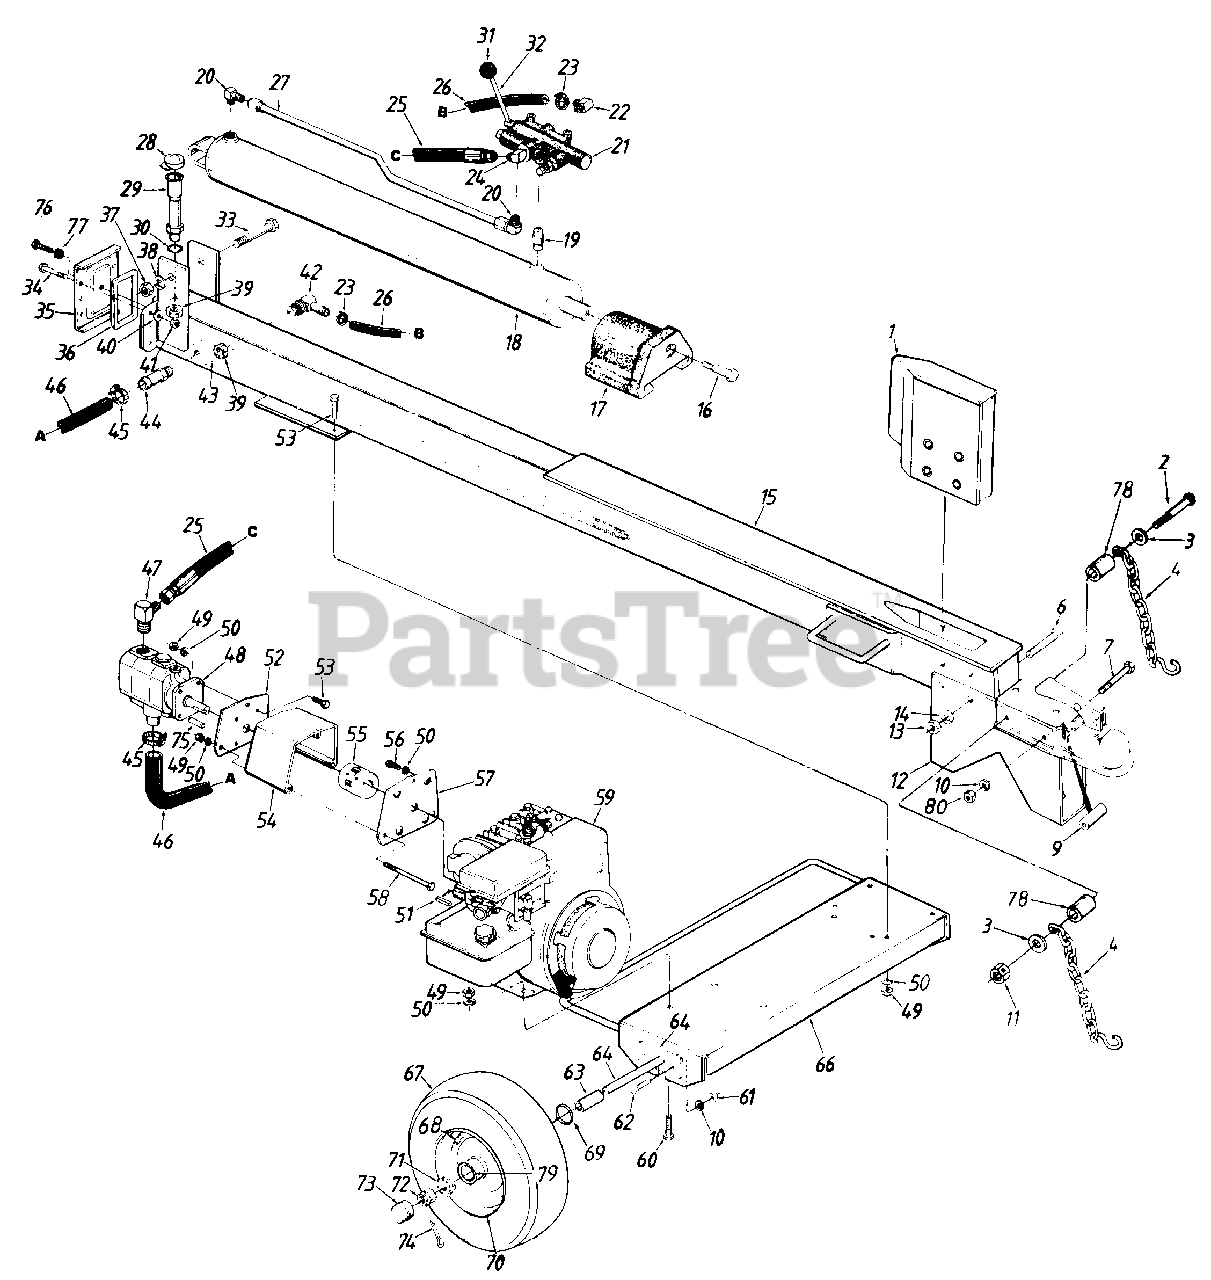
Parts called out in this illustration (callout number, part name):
1	Wedge Ass'y.
2	Hex Bolt 3/8-16 x 4.5" Lg. (Gr. 5)
3	Fl-Wash. .375" I.D. x .87" O.D.
4	Chain - Tow Hitch
6	Hex Bolt 5/8-18 x 3.5" Lg.
7	Hex Bolt 3/8-16 x 3.25" Lg. (Gr. 8)
8	Tow Hitch Ass'y.
9	Spacer .375" I.D. x .625" O.D.
10	L-Wash. 3/8" I.D.
11	Hex Cent. L-Nut 3/8-16 Thd.
12	Beam Stand
13	Hex Nut 5/8-18 Thd.
14	L-Wash. 5/8" I.D.
15	Oil Tank Ass'y.
16	Shld. Bolt .62" Dia. x .475"
17	Pusher Plate
18	Hydraulic Cylinder
19	Pipe Nipple 1/2" NPT x 2" Lg.
20	90° Solid Male Adapter
21	Control Valve
22	Return Elbow
23	Adjustable Hose Clamp
24	90° Solid Male Adapter
25	High Pressure Hydraulic Hose 29.5" Lg.
26	Return Hose 3/4" I.D. x 23-1/2" Lg.
27	Metal Pressure Tube
28	Cap
29	Filler Tube Ass'y.
30	O-Ring .92" I.D.
31	Ball Knob
32	Control Handle
33	Hex Bolt 3/4-10 x 4.5" Lg.
34	Hex Bolt 5/16-18 x 1.5" Lg.
35	Beam End Plate
36	Gasket
37	Hex Nut 3/4-10 Thd.
38	L-Wash. 3/4" I.D.
39	Hex Nut 1-1/16-12 Thd.
40	Fl-Wash. .34" I.D. x .68" O.D.
41	Hex L-Nut 5/16-18 Thd.
42	90° Adapter 3/4" Hose
43	Strainer Tube Ass'y.
44	Adapter 1" x 1-1/16-12 Thd.
45	Hose Clamp 5/8"
46	Suction Hose 1" I.D.
47	90° Adapter
48	Two Volume Pump (Incl. Ref. 75)
49	Hex Nut 5/16-24 Thd.
50	L-Wash. 5/16" I.D.
51	Sq. Key 3/16 x .75" Lg.
52	Rear Coupling Support Bracket
53	Hex Bolt 5/16-24 x 1.0" Lg.
54	Coupling Shield
55	Flexible Coupling
56	Hex Bolt 5/16-24 x .62" Lg.
57	Front Coupling Support Bracket
58	Hex Bolt 5/16-24 x 4.0" Lg.
59	Engine
60	Hex Bolt 5/16-24 x 1.75" Lg.
61	Hex Nut 3/8-24 Thd.
62	Hex Bolt 3/8-24 x 1.0" Lg.
63	Spacer .75" I.D. x 1.12" O.D.
64	Axle Assembly
66	Engine Frame Ass'y.
67	Wheel Ass'y. Comp.
67	Tire Only
68	Air Valve
69	Bearing Seal
70	Rim Only
71	Bearing Cone
72	Hex Slotted Nut 3/4-16 Thd.
73	Hub Cap
74	Cotter Pin 5/32" Dia.
75	Hi-Pro Key 1/8" x 1/2" Lg.
76	Hex TT-Tap Scr. 5/16-18 x .62" Lg.
77	Gasket Washer 5/16" I.D. x 3/4" O.D.
78	Spacer .375" I.D. x .625" O.D.
79	Bearing Cup
80	Hex Nut 3/8-16 Thd. (Gr. 5)
